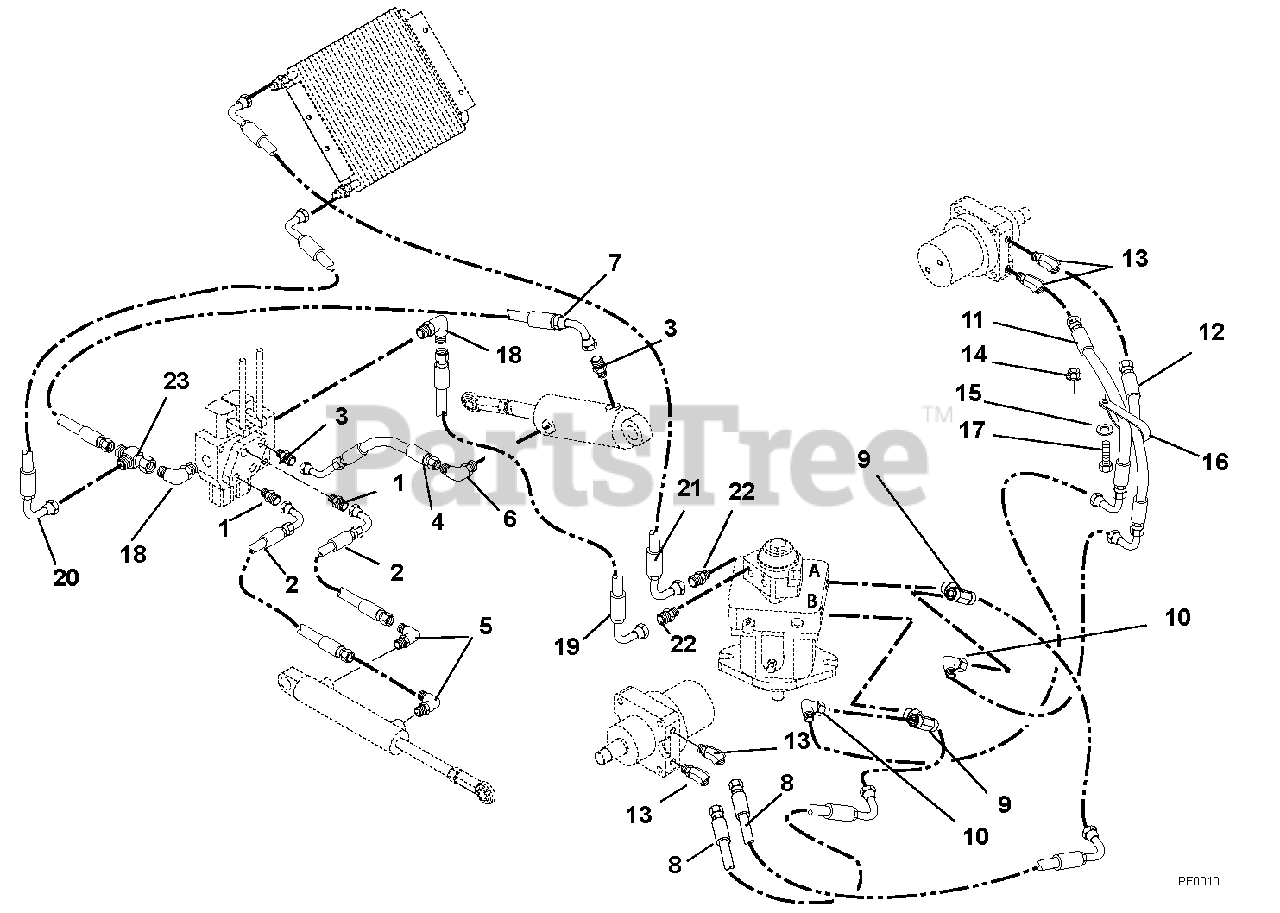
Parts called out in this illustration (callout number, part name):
1	Fitting, Hydraulic
2	Hose, Hydraulic
3	Fitting, Hydraulic
4	Hose, Hydraulic
5	Fitting, Hydraulic (990024)
6	Fitting, Hydraulic
7	Hose, Hydraulic
8	Hose, Pump To Motor, .50-22-2K F08F0-F08F9
9	Fitting, Hydraulic Tee, M80-M80-M80
10	Fitting, Hydraulic 90 EL
11	Hose, Pump To Motor .50-26-2K F08F0-F08F9
12	Hose, Hydraulic .50-24-2K F08F0-F08F9
13	Fitting, Hydraulic
14	Nut, Locking Top Flange .38-16
15	Washer, Flat Steel .406 x .812 x .065
17	Bolt, Hex .38-16 x 1.00 Grade 5
18	Fitting, Hydraulic Elbow
19	Hose, Hydraulic
20	Hose, Hydraulic
21	Hose, Hydraulic
22	Fitting, Hydraulic
23	Fitting, Hydraulic
